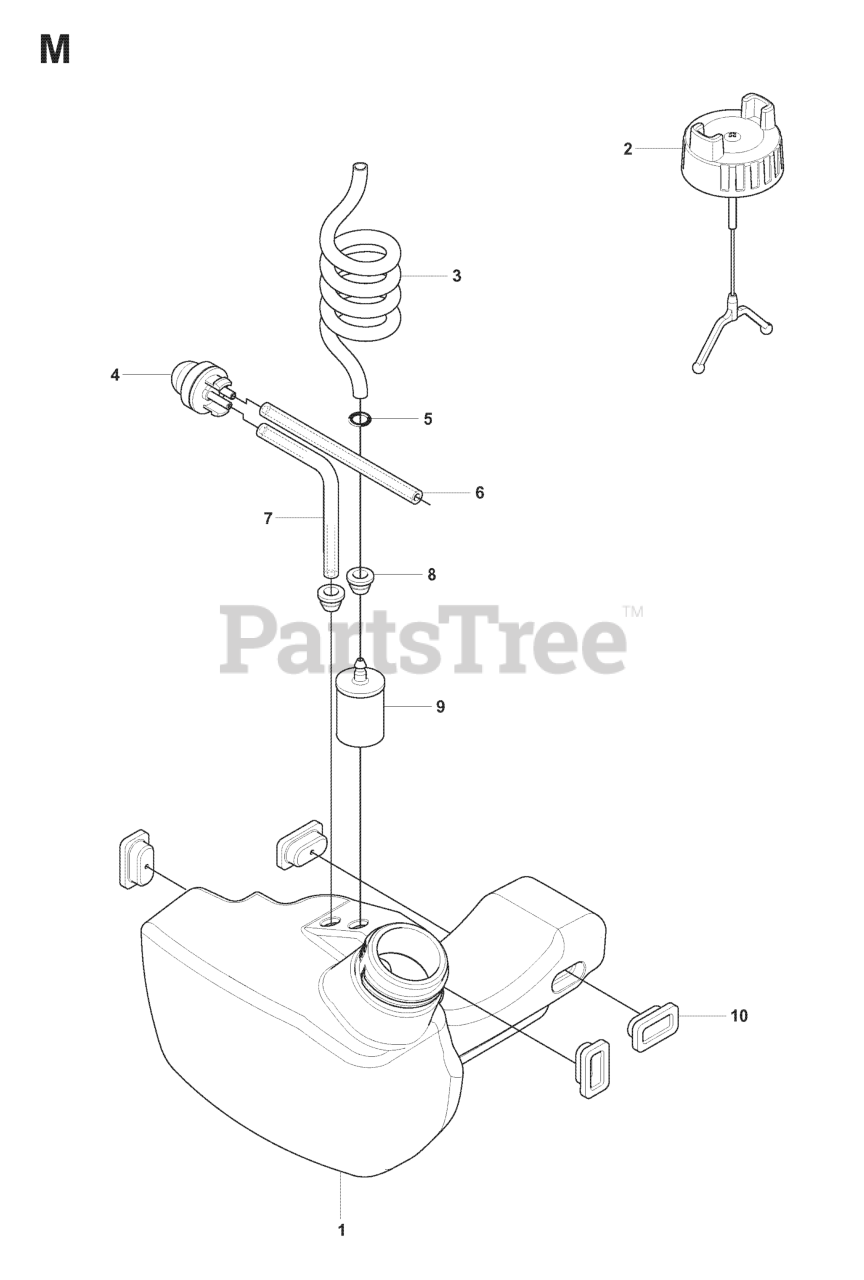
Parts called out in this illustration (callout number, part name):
2	%FUEL CAP
3	FUEL HOSE
4	AIR PURGE BUBBLE
8	FUEL TANK BUSHING
9	RP FUEL FILTER
